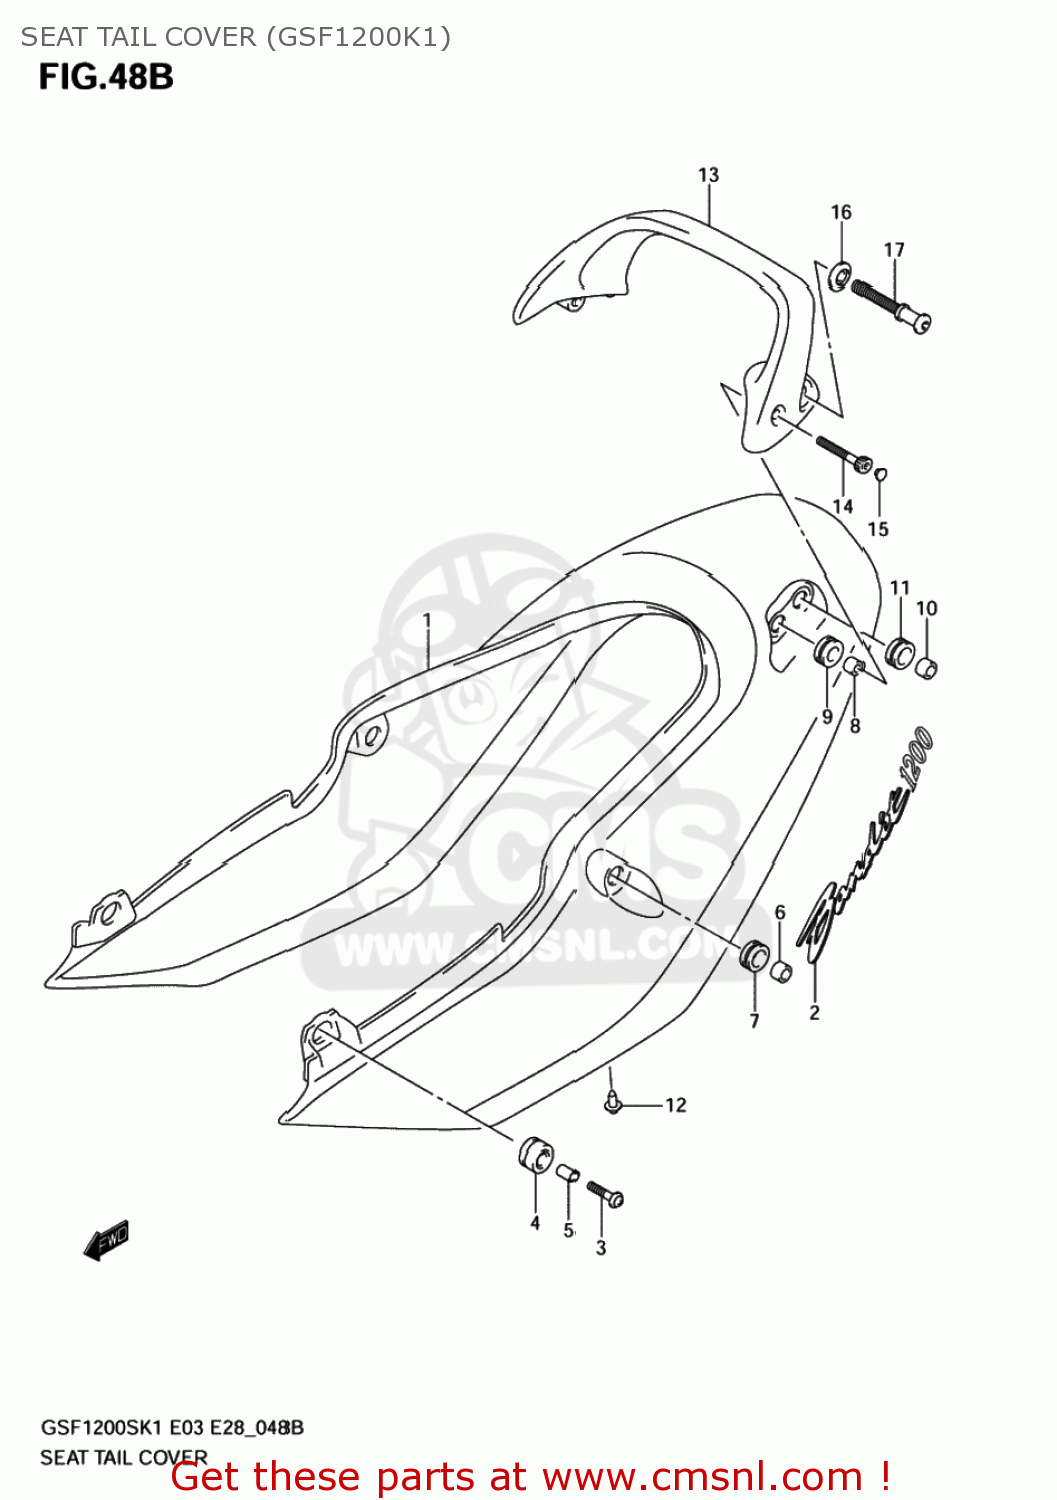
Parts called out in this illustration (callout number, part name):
1	COVER,SEAT TAIL(RED)
2	EMBLEM,SEAT TAIL COVER
3	SCREW(6X30)
4	CUSHION,SEAT TAIL COVER FR
5	SPACER(6.5X10X13)
6	SPACER,8.5X14X9
7	CUSHION
8	SPACER(6.5X12X9)
9	CUSHION
10	SPACER,8.5X14X9
11	CUSHION
12	CLIP(BLACK)
13	HANDLE,PILLION RIDER
15	CAP(OD:10)
16	WASHER,HOOK
17	HOOK,PILLION RIDER HANDLE
